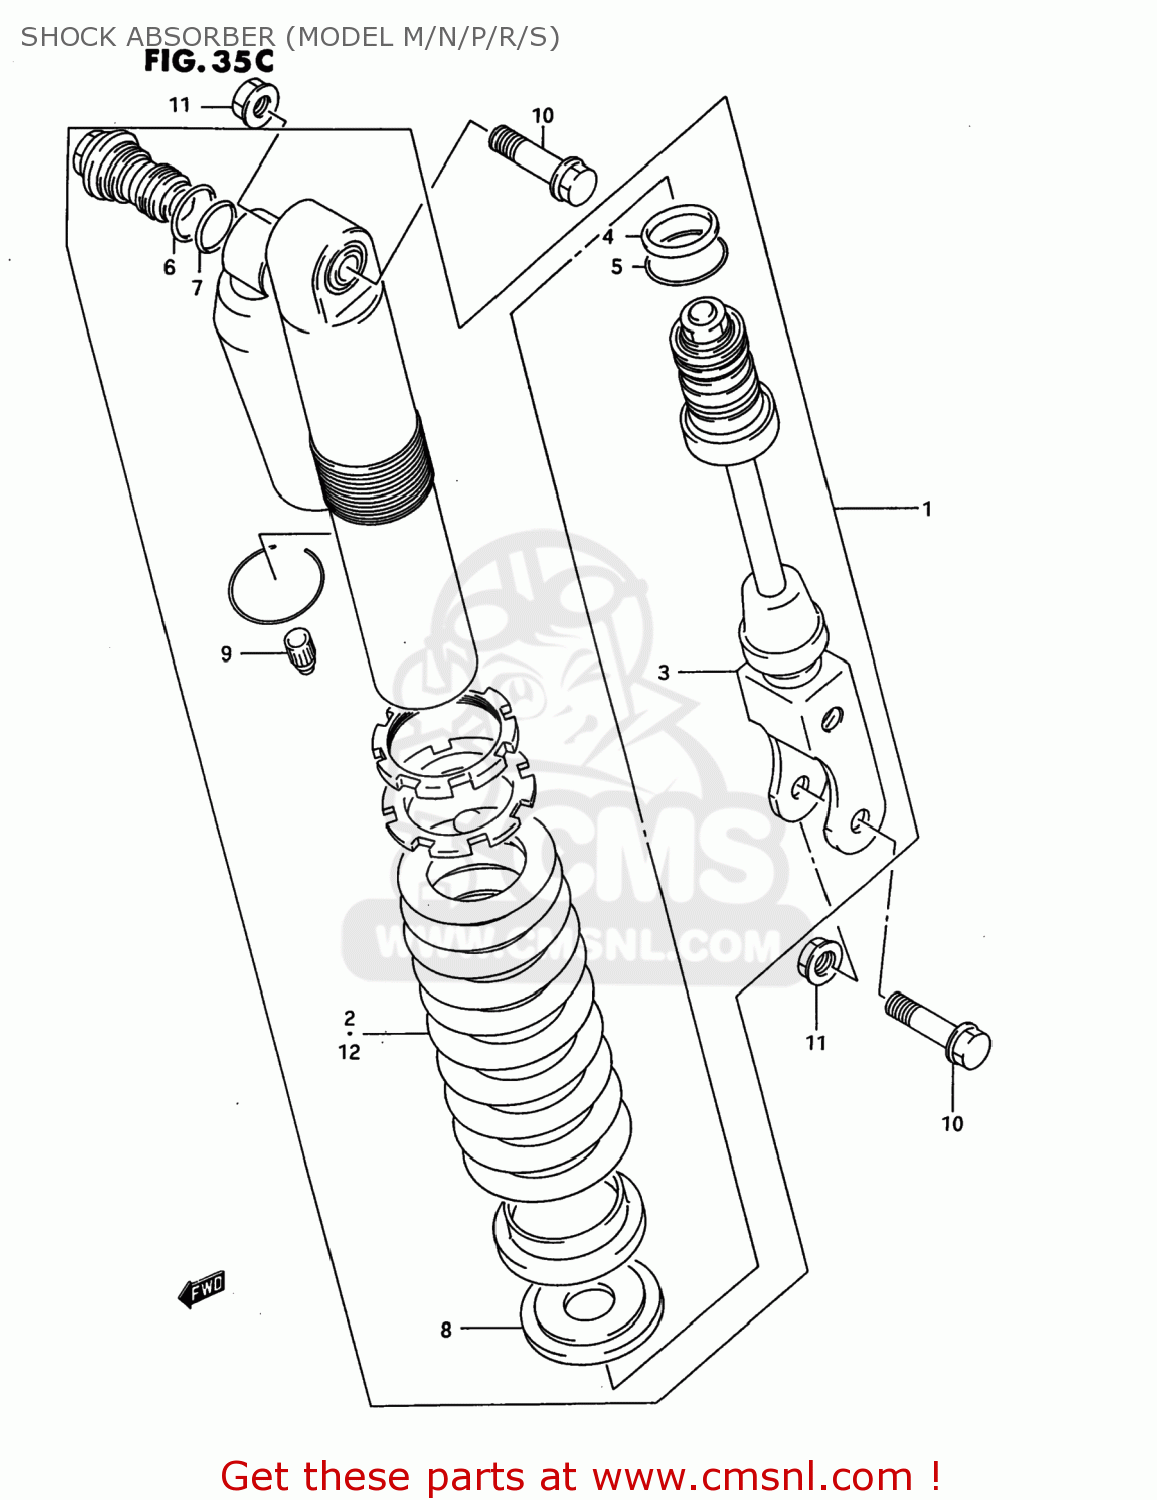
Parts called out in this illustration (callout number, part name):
1	ABSORBER ASSEMBLY,REAR SHOCK
2	SPRING
3	ROD,PISTON
4	O RING
5	RING,PISTON ROD STOPPER
6	O RING
7	O RING
8	SEAT,SPRING STOPPER
9	CAP
10	BOLT,RR CUSHION ROD UPR
11	NUT
12	SPRING(SOFT)
